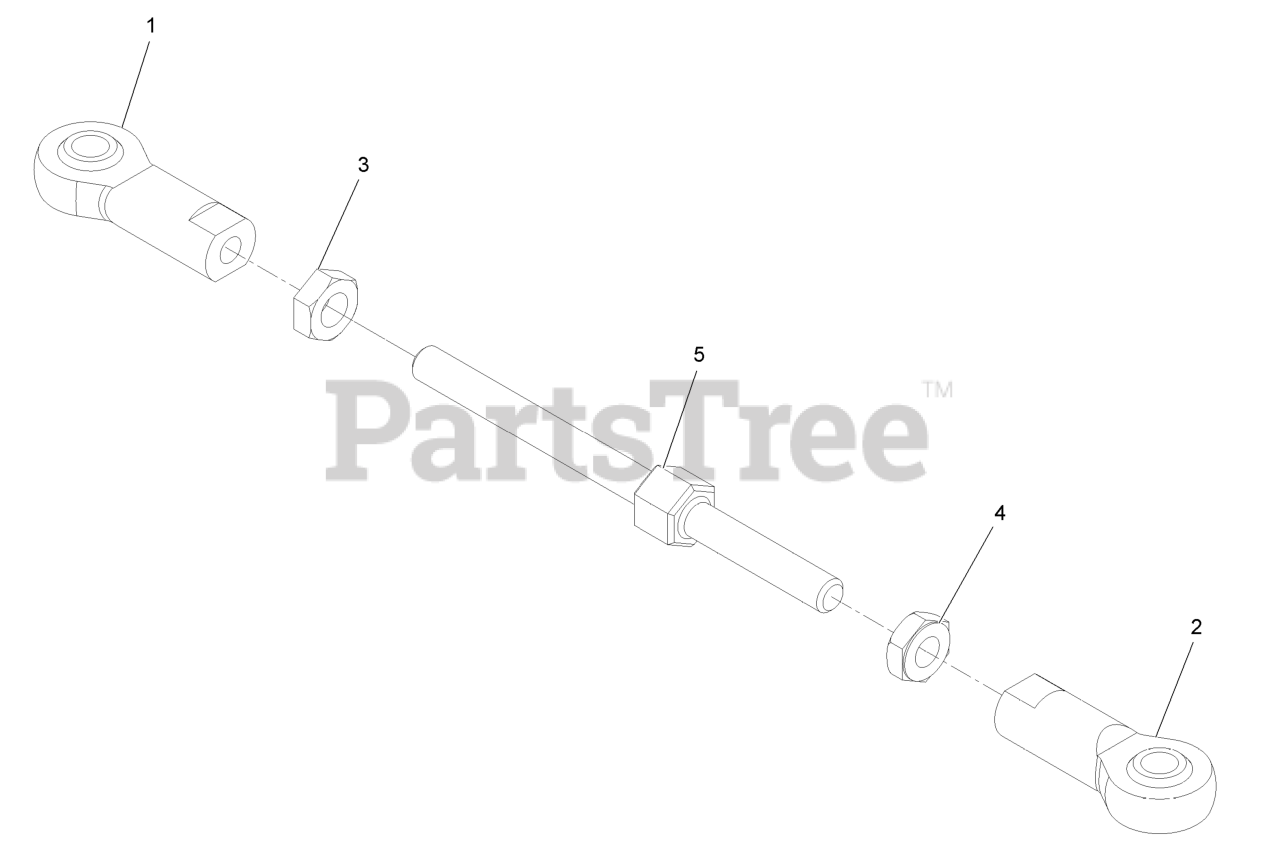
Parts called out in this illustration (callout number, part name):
1	ROD END-BALL JOINT
2	JOINT-BALL, LH
3	NUT-JAM
4	NUT-JAM
5	ROD-VERTICAL ADJUST
